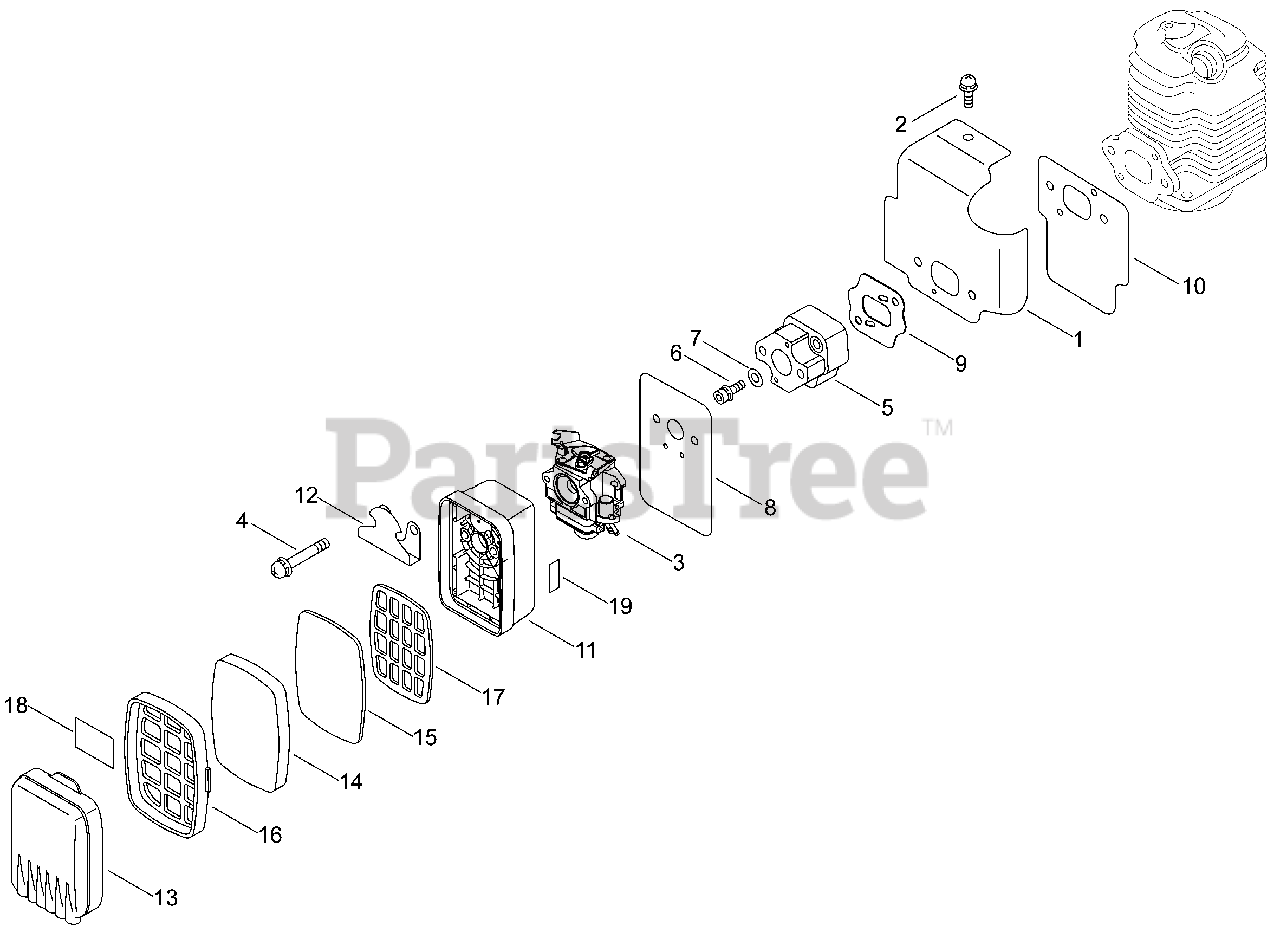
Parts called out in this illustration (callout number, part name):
1	COVER, ENGINE - INTAKE
2	SCREW 5×10
3	CARBURETOR - WYK-496
4	SCREW 5×60
5	INSULATOR, INTAKE
6	BOLT 5×30
7	WASHER 5.5×10×2.3
8	GASKET, INTAKE
9	GASKET, INTAKE
10	GASKET, INTAKE
11	CASE ASSY, AIR FILTER
12	PLATE, PREVENT
13	COVER, AIR FILTER
14	PRE-FILTER, FOAM
15	FILTER, AIR
16	GRID, PRE-FILTER
17	GRID, AIR FILTER
18	LABEL, AIR FILTER
19	LABEL, CHOKE
